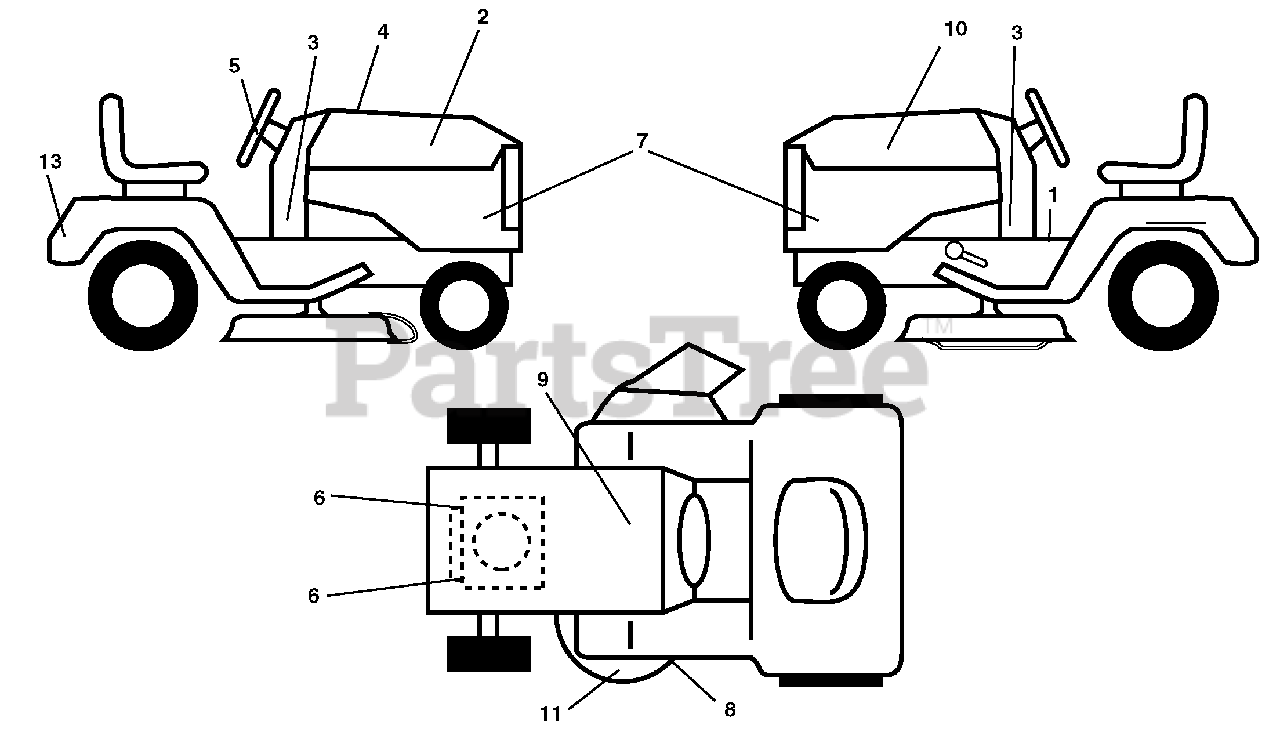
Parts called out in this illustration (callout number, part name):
1	Decal, Operator's
2	Decal, Hood RH
3	Decal, Dash Lower
4	Decal, Replacement
5	Decal, Strg Whl
6	Decal, Engine HP
7	Decal, Side Panel
8	Decal, Mower Sch.
9	Decal, Battery Dnge/Poi
10	Decal, Hood LH
11	Decal, Mower Caution
12	Decal, Fender
13	Decal, Bypass
14	Pad, Footrest, RH
15	Pad, Footrest, LH
17	Manual, Operator's E&SP
19	Manual, Parts
